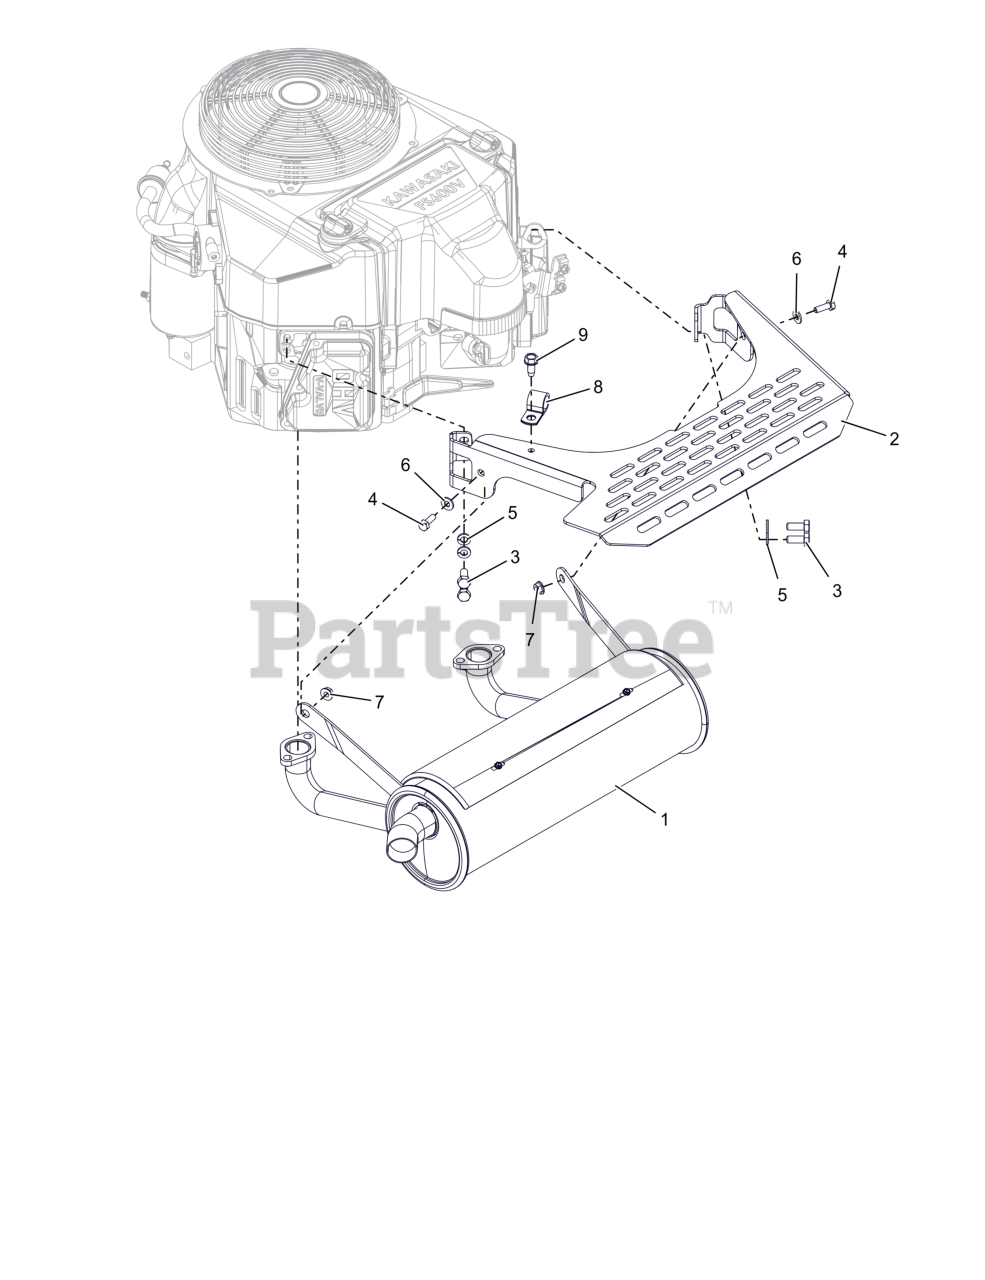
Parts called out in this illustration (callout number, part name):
1	MUFFLER, KAW FS PROWALK
2	SHIELD, MUFFLER
3	BLT, HEX M8-1.25X20 G8.8 ZCC
4	BLT, HEX .25-20X.75 G5 ZCC
5	WSHR,LK-REG .312X.078 ZCC
6	WSHR,FLT .281X.625X.065 ZCC
7	NUT-LK-CTR-FLG .25-20 ZC120
8	CLAMP, CUSHIONED STEEL .75
9	SCR,TAP .312-18X.75 HWH TR ZCC
